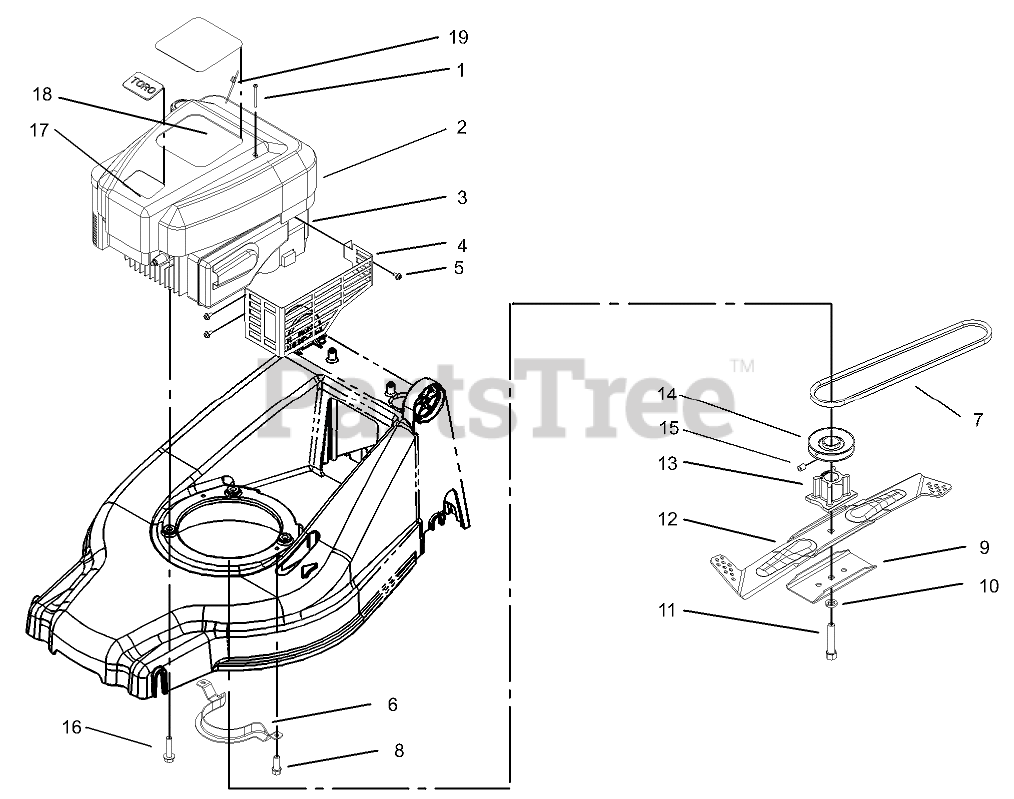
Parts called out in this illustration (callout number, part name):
1	SCREW-PPH
2	SHROUD-ENGINE
4	SHIELD-MUFFLER
5	SCREW-HWH
6	GUIDE-BELT, ENGINE
7	V-BELT
8	SCREW-HWH
9	STIFFENER-BLADE
10	WASHER-LOCK
11	BOLT-BLADE
13	RETAINER-BLADE
14	PULLEY ASM
15	SCREW-SET
16	SCREW-HWH
17	PLATE-LOGO
18	DECAL-ENGINE
19	STOP-ROPE
